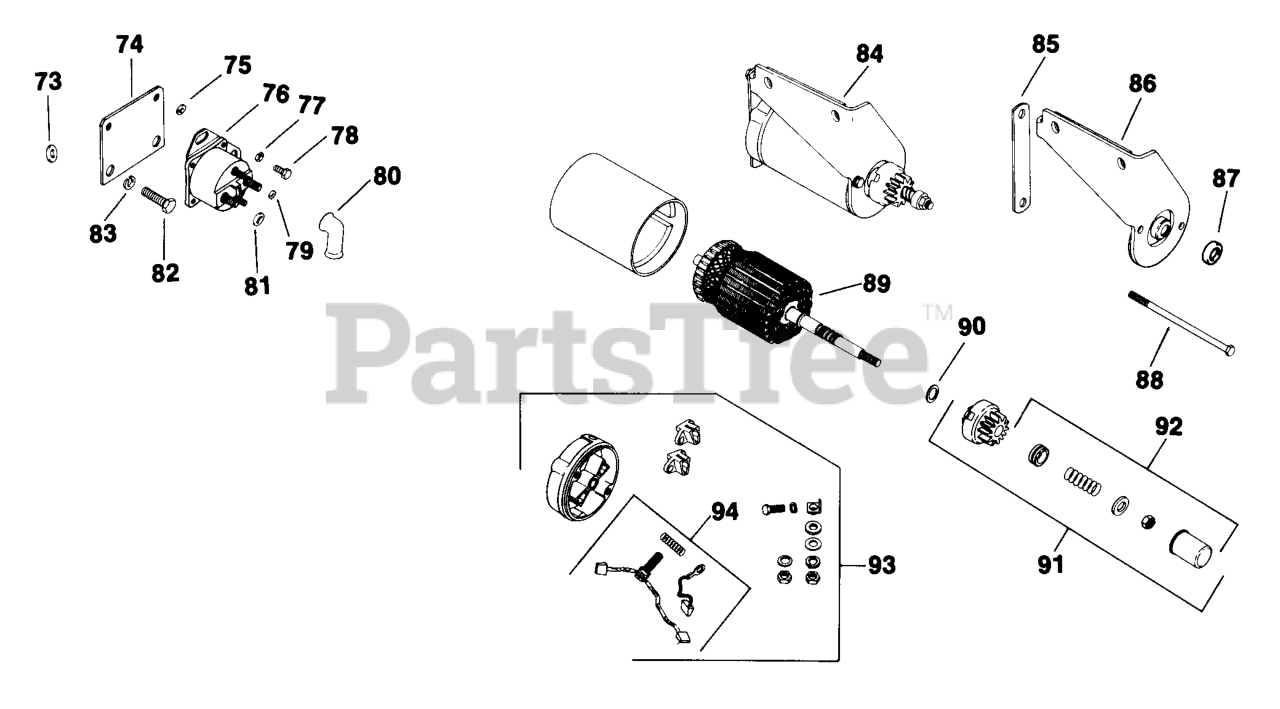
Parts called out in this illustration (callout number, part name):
82	SCREW, CAP HD 3/8-16x1"
83	WASHER, SPRING LOCK 3/8"
84	STARTER - USE 41 098 07
87	BEARING - DISCONTINUED
88	BOLT - DISCONTINUED
90	WASHER - DISCONTINUED
91	DRIVE KIT - USE 41 755 34
93	CAP - DISCONTINUED
94	KIT - USE 52 755 15
